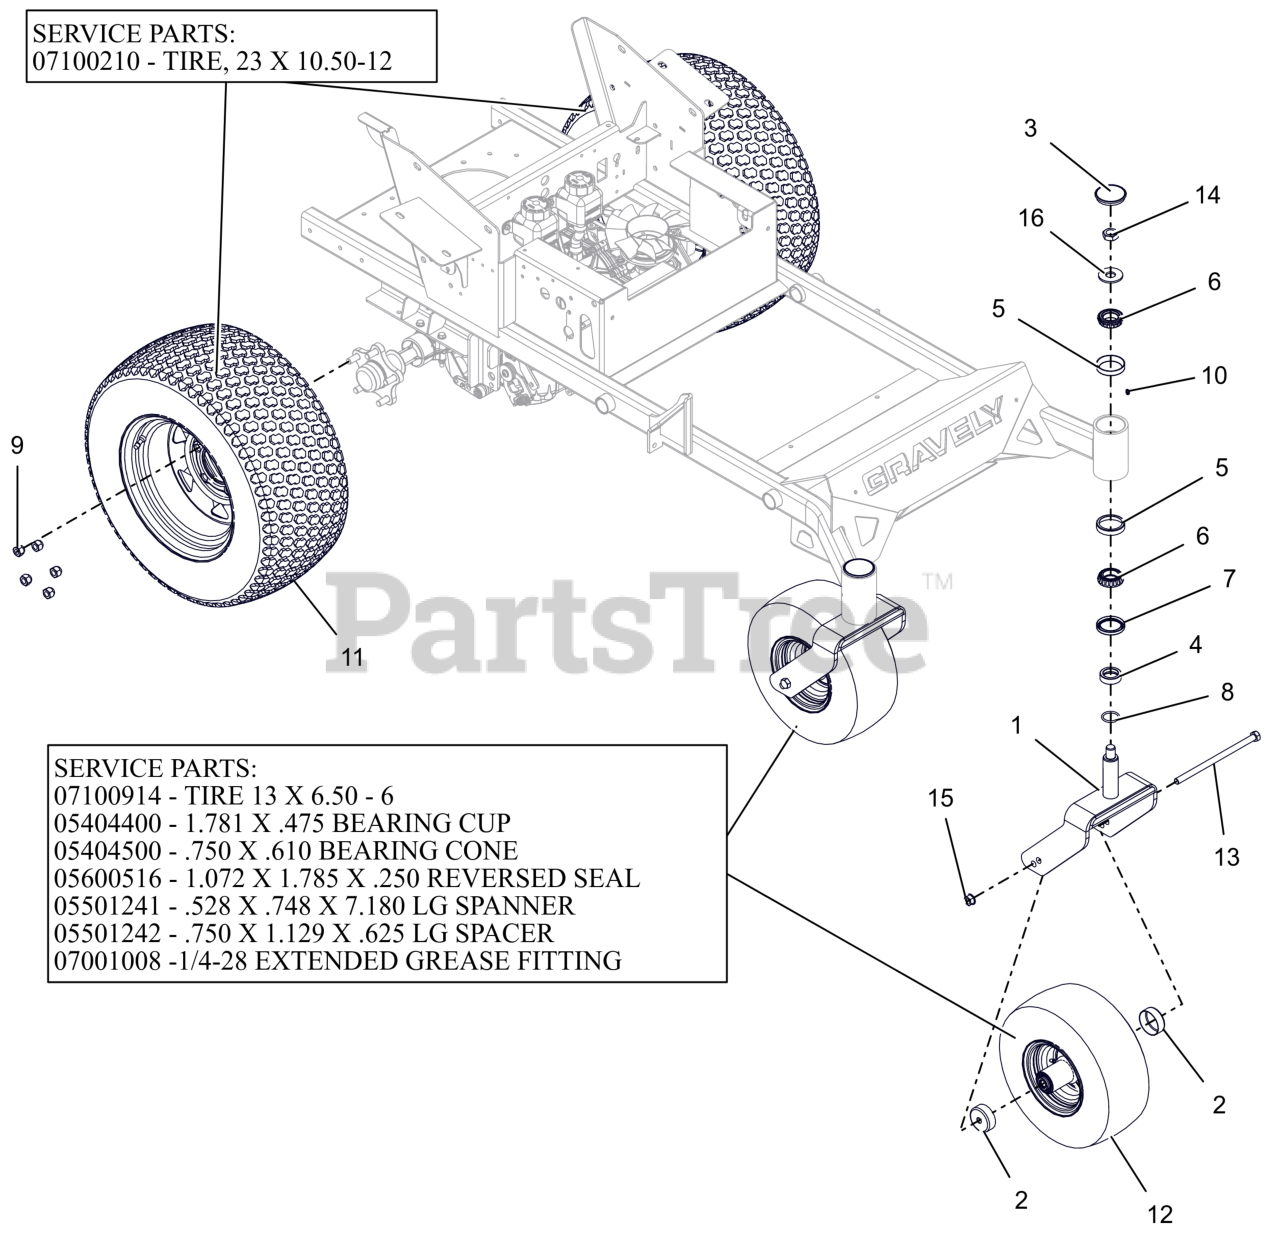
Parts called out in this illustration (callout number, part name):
1	CASTER FORK WMT - RED
2	SHIELD, WHEEL BEARING
3	CAP, DUST
4	SPCR, FRONT CASTER FORK
5	BRG-CUP 2.328X.465
6	BRG-CONE 1.25X.66
7	SEAL, OIL 1.75 X 2.332 X .312
9	NUT, WHEEL .50-20 ZCC
10	FTG, .25-28 FLUSH MNT GREASE
11	ASM, WHL/TIRE 23X10.50-12 K500
11	TIRE, 23X10.00-12
11	TUBE 22,23&24X8.50/9.50/10.00/10.50/12.00-12
12	ASM, WHL/TIRE 13X6.50-6 SMOOTH
12	TIRE, 13X6.50-6 SMOOTH
12	BRG-CUP 1.781X.475
12	BRG-CONE .750X.61
12	SEAL,1.072X1.785X.250 REVERSED
12	SPANNER, .528X.748X7.18 LG
12	SPACER, .750X1.129X.625 LG
12	GREASE FITTING 1/4-28 EXTENDED
13	BLT, HEX .50-13X9.00 G5 ZCC
14	NUT, JAM-TOPLOCK .750-16 ZCC
15	NUT-LK-TOP-FLG .500-13 GF ZCC
16	WSHR-FL-STL 0.812X2X0.148 ZCC
